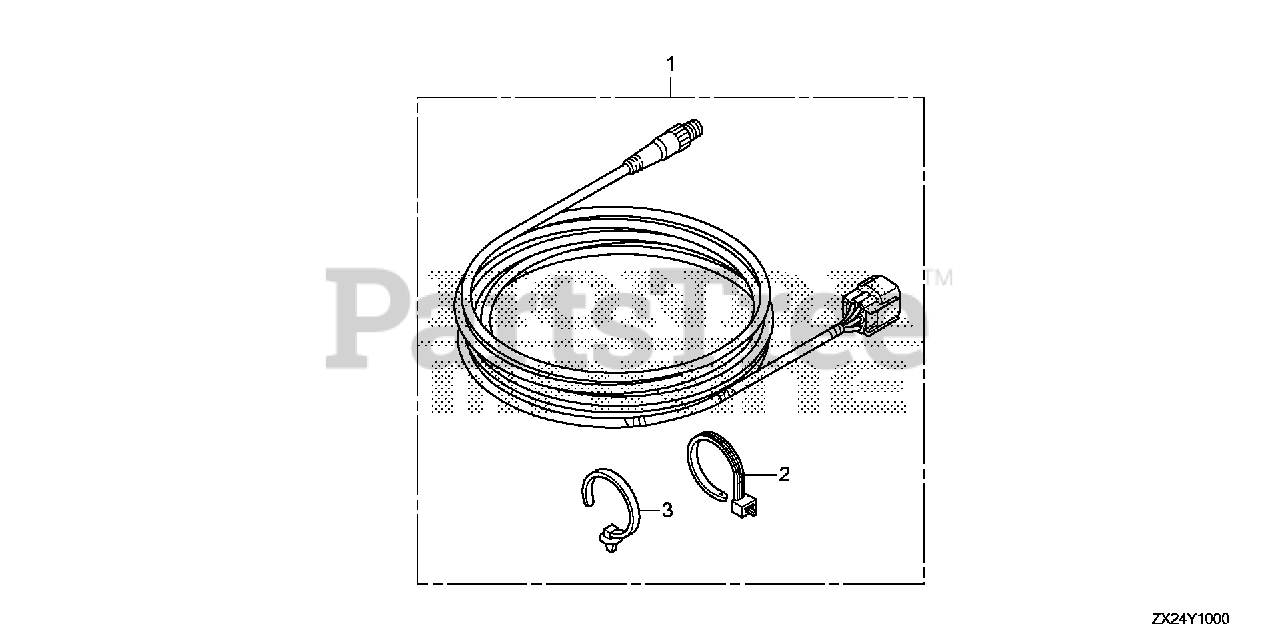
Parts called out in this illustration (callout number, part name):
1	KIT, CABLE (6FT) (NMEA)
2	TIE, CABLE
3	CLIP, HARNESS BAND (155.3MM) (BLACK)
